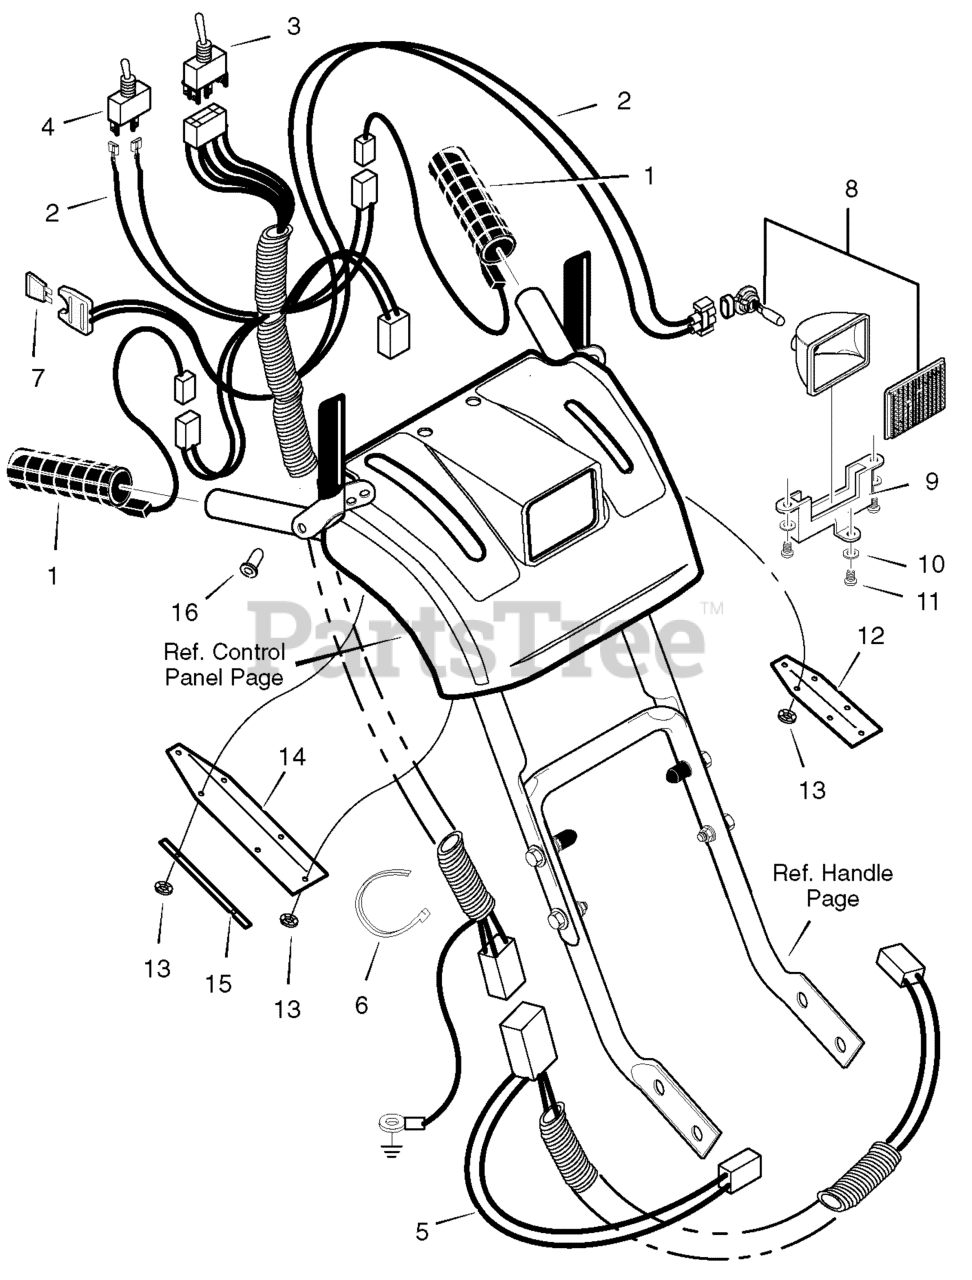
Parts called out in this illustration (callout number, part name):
1	GRIP, HEATED
2	WIRE HARNESS, UPPER
3	SWITCH, CHUTE ROTATION
4	SWITCH, HEATED GRIP
5	WIRE HARNESS, LOWER
6	TIE, CABLE
7	FUSE, 7.5 AMP AUTOMOTIVE
8	HEADLIGHT ASSEMBLY
9	BRACKET
10	WASHER, FLAT
11	SCREW #8 X .50
13	NUT, PUSH
16	RIVET, 0.125 x 0.23
